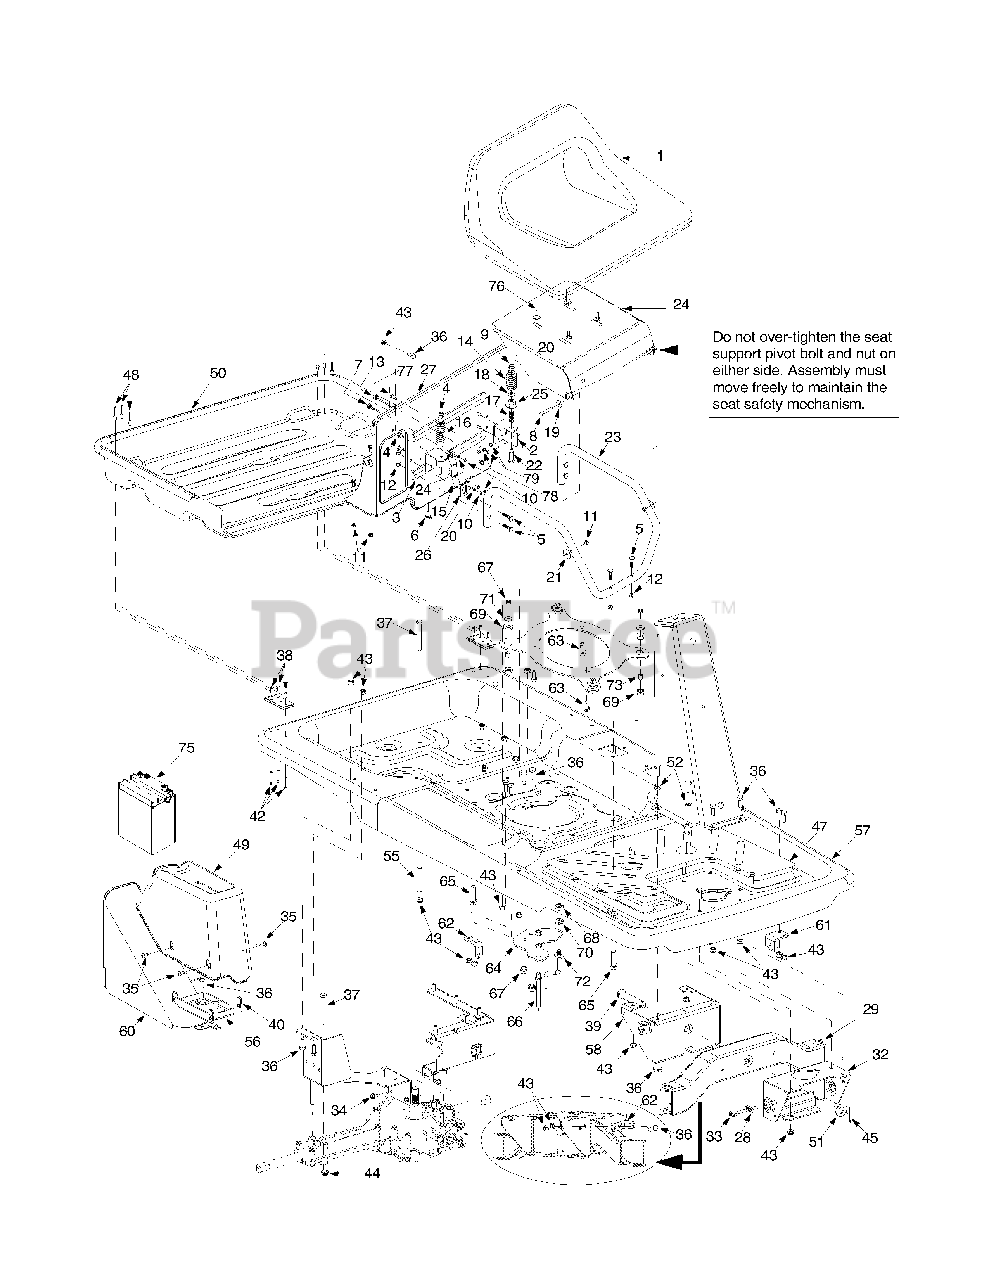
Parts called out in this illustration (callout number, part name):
5	Carriage Bolt 5/16 x 1.5"
6	Hex Bolt M8-1.25: 20
7	Special Screw M6-1: 16
8	Hex Bolt M8-1.25: 45
9	Flange Lock Nut 3/8-16
10	Hex Nut M6-1
11	Hex Lock Nut M8-1.25
12	Flange Lock Nut 5/16-18
13	Ratchet Clip
14	Compression Spring
15	Actuator Spring
16	Compression Spring
17	Compression Spring
18	Bell Washer .375 x .870 x .063
19	Shoulder Bushing
20	Lock Washer
21	Flat Washer 8.4 x 35
22	Shoulder Screw
26	Bag Switch Bracket
27	Seat Support Bracket
28	Switch Plate
34	TT Screw 1/4-20 x 0.5"
35	Machine Screw
36	Hex Screw M8-1.25: 20
37	Special Screw
38	Special Screw
39	Clevis Pin
40	Speed Nut 1/4-20
42	Hex Nut
43	Hex Lock Nut
44	Flange Lock Nut
45	Cotter Pin
47	Foot Pad
49	Battery Cover
50	Bag Tray
51	Flat Washer .64 x 1.24 x .06
52	Flat Washer 8.4 x 16
53	Lock Washer M4
55	Spacer
56	Bracket: Battery Support
61	Stop Bracket: Pivot
62	Cable Bracket
63	TT Sems Screw 3/8-16 x 1.0
64	Belt Keeper Bracket
65	Hex Bolt M8-1.25: 30
66	Pin: Belt Guard
67	Lock Nut M8-1.25
68	Hex Nut 5/16-18
69	Engine Mount: Gromm.
70	Lock Washer 5/16
71	Flat Washer 8.4 x 24
72	Belt Keeper Rod
73	Spacer
76	Self-Tapping Screw 3/8-16 x .625
77	Self-Tapping Screw 1/4-20 x 0.75
78	Lock Washer
79	Hex Sems Nut 1/4-20
